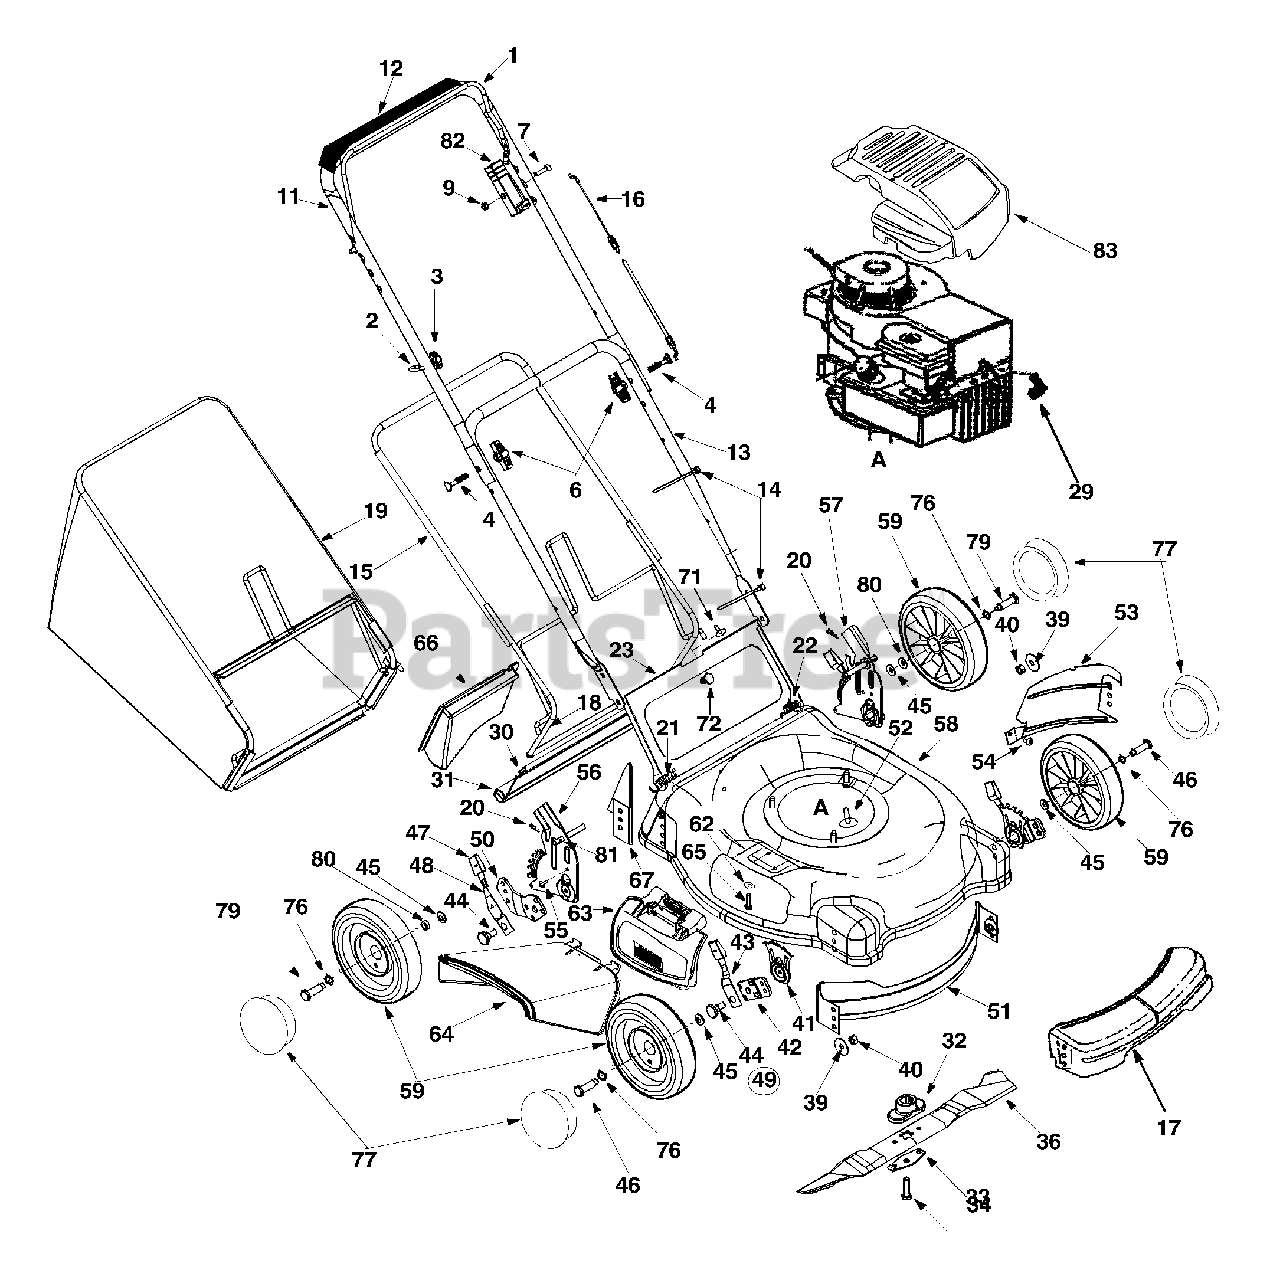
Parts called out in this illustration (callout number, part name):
1	Control Handle Assembly
3	Handle Knob 1/4-20 Thd.
4	Curved Hd. Bolt 5/16-18 x 2" Lg.
7	Oval C-Sunk Mach. Scr.
9	Hex L-Nut 1/4-20 Thd.
14	Cable Tie
16	Control Cable - 39"
17	Front Cover: Gray
20	Int. Cotter Pin 5/16" Dia.
21	Door Spring - R.H.
22	Door Spring - L.H.
30	Wire Rod
31	Rear Flap
32	Blade Adapter
33	Hex Bolt 3/8-24 x 1.5" Lg.
34	Blade Bell Support
36	21" Mulching Blade
39	Bell-Wash. .39" I.D. x 1.38"
40	Hex Nut 3/8-16 Thd.
41	Height Adj. Plate
43	Front Spring Lever Ass'y. w/Knob
44	Shld. Bolt .5" Dia. x .357"
45	Bell-Wash. .38" I.D. x .88" O.D.
46	Front Axle Bolt
47	Spring Lever Knob
48	Rear Spring Lever
49	Height Adj. Assy. Comp. - RH
50	Pivot Bar R.H.
54	Torx Mach AB-Tap Scr. 1/4 x.62"
55	Hex Ind Wash. Scr. 1/4-14:.625
56	Handle Brkt. Ass'y. - RH
57	Handle Brkt. Ass'y. - LH
62	Bell-Washer 1/4" I.D.
63	Hinged Mulching Plug
64	Chute Deflector: Side Discharge
65	Hex Hd Self-Tp Scr. 1/4-20 x .5" L.
66	Mulching Baffle Plug
71	Truss Scr. #10-24 x .38" Lg.
76	Wave Washer
77	Hub Cap - Rad. Spoke - Grey
79	Rear Axle Bolt
80	Spacer
81	Weld Pin
82	Throttle Housing w/o Lever
83	Engine Shroud: Oyster Gray
